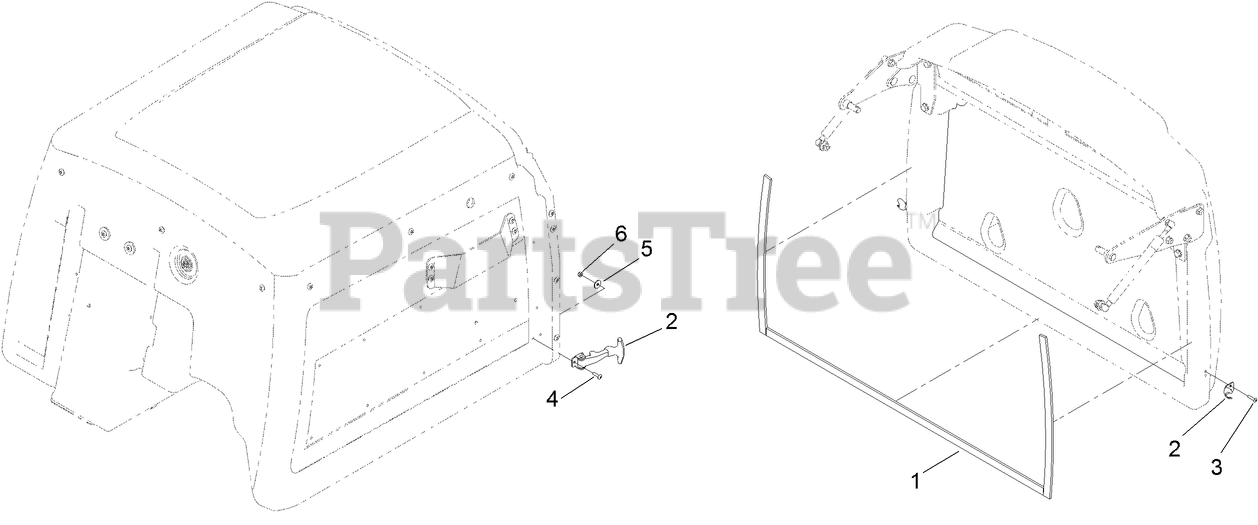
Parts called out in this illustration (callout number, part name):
1	SEAL-FOAM
2	LATCH-FLEX, DRAW
3	RIVET-TRIFOLD
4	SCREW-HEAD, TRUSS
5	WASHER-FLAT
6	NUT-LOCK, NI
